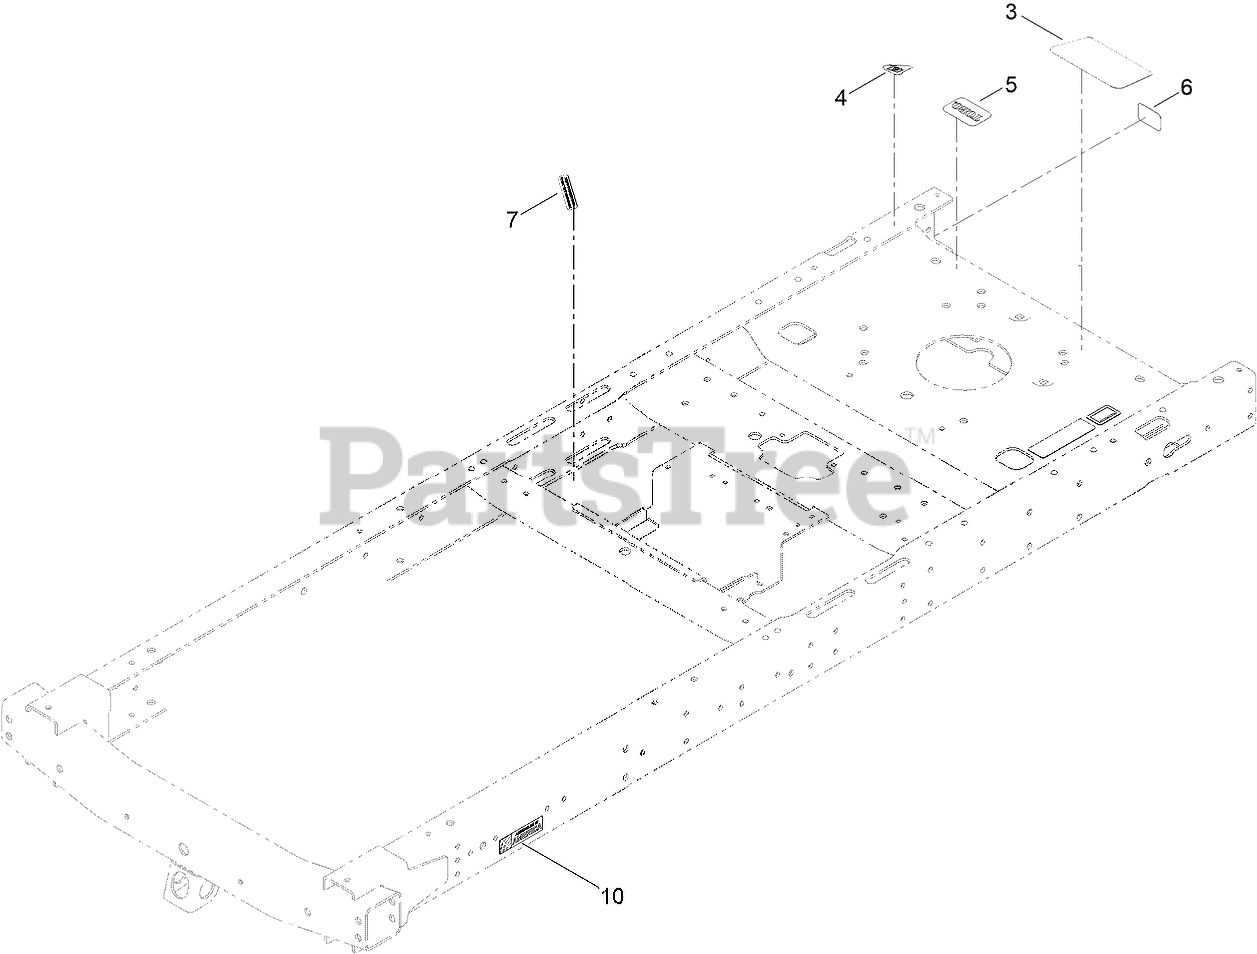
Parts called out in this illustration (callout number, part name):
3	DECAL-ENGINE
4	DECAL-DRAIN, OIL
6	PLACARD-INTAKE
7	DECAL-SHUTDOWN
